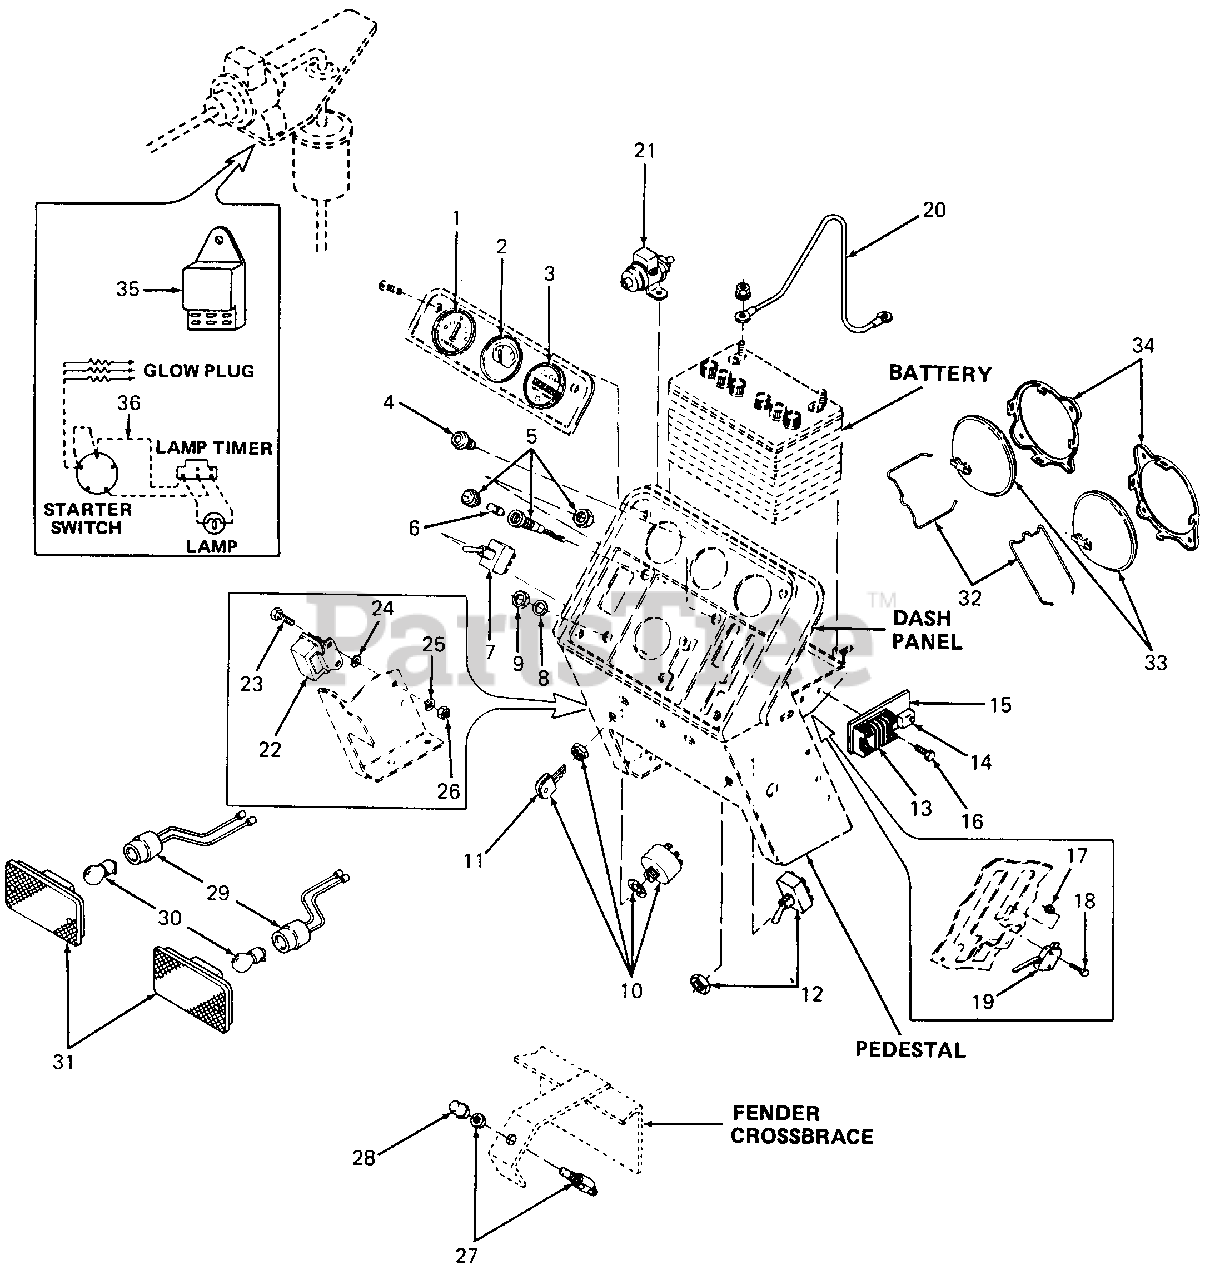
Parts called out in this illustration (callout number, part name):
1	Ammeter
2	Gauge, Water Temperature
3	Hourmeter
4	Indicator Lamp, Glow Plug
5	Light Assy, Oil Indicator
6	Bulb, Light
7	Switch, PTO
8	Washer, Flat, .531 X .680 X .054 Thk
9	Nut, Hex, 1/2-27 X 1.00 Thk
10	Switch, Key
11	Key, Ignition (Set of 2)
12	Light Switch w/Nut
13	Regulator
14	Circuit Breaker
15	Bracket, Circuit Breaker
16	Screw, Hex Cap, 1/4-20 X 1.50 Lg
17	Nut, Hex Insert Lock, #4-40
18	Screw, Hex Mach, #4-40 X .75 Lg
19	Switch, Reverse
20	Wire, Electric, 14.0 Lg - Black
21	Pump, Electric Fuel
22	Relay
23	Screw, Hex Cap, 1/4-20 X .62 Lg GR5
24	Washer, External Lock, 1/4
25	Washer, Lock, 1/4
26	Nut, Hex, 1/4-20 GR5
27	Switch w/Nut
28	Boot, Switch
29	Cable Assy, Tail Light
30	Bulb, Light
31	Lens Assy, Tail Light
32	Spring, Headlight Retaining
33	Headlight
34	Retainer, Headlight
36	Harness, Lamp Timer
